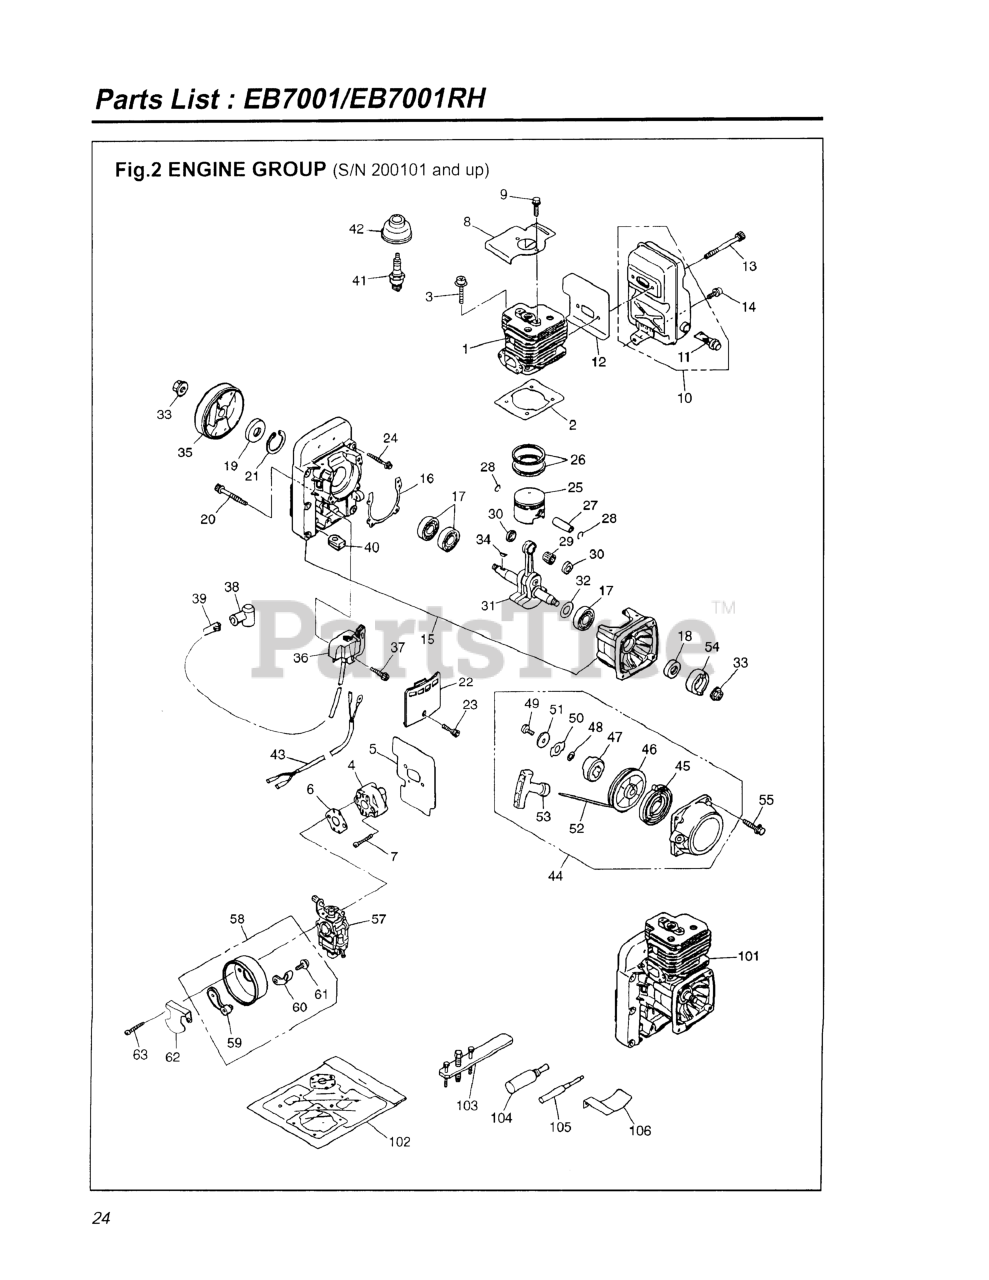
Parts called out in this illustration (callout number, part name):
1	CYLINDER (REPLACES 2750-12110)
2	GASKET, BASE
3	BOLT, M5 X 22
4	INSULATOR (REPLACES-13160)
5	GASKET
6	GASKET, CARB (RPLS -13131)
7	BOLT
8	COVER
9	BOLT, M5 x 10
11	ARRESTER
12	GASKET
13	BOLT, M6 X 70
14	BOLT, M6 X 12
15	CRANKCASE (RPLS. 2750-21100)
16	GASKET
17	BEARING (REPLACES 2810-21240)
18	SEAL, OIL 15 X 25 X 7
19	SEAL (REPLACES 1400-21220)
20	BOLT, M5 X 30
21	RING, SNAP, M35 X 1.5
22	COVER
23	BOLT, M4 X 16
24	BOLT, M6 X 40
25	PISTON
26	RING
27	PIN, PISTON
28	RING, SNAP
29	BEARING
30	WASHER (RPLS 1491-41510)
32	SHIM (REPLACES 848-870-G000)
33	NUT, M10
34	KEY
35	ROTOR (REPLACES -71110)
36	COIL ASSEMBLY, IGINITION
37	BOLT, M4 x 20
38	CAP
39	SPRING
40	GROMMET
42	CAP
43	CORD COMP.
44	RECOIL ASSY
45	SPRING (RPLS -75220)
46	REEL
47	DOG
48	WASHER
49	SCREW
50	RETAINER (RPLS 1861-75161)
51	WASHER
52	ROPE
53	KNOB
54	PULLEY (RPLS -75210)
55	BOLT, M5 x 20
57	CARBURETOR (WYK-123-1)
58	CASE ASSY (RPLS -82400)
59	PLATE (RPLS -82420)
60	LEVER (RPLS -82430)
61	SCREW (RPLS- 82440)
62	PLATE
63	SCREW (RPLS 0263-30550)
102	KIT, GASKET
103	PULLER ASSY
104	STOPPER (TOOL) (RPLS 3320-9641
105	PULLER, PISTON PIN
